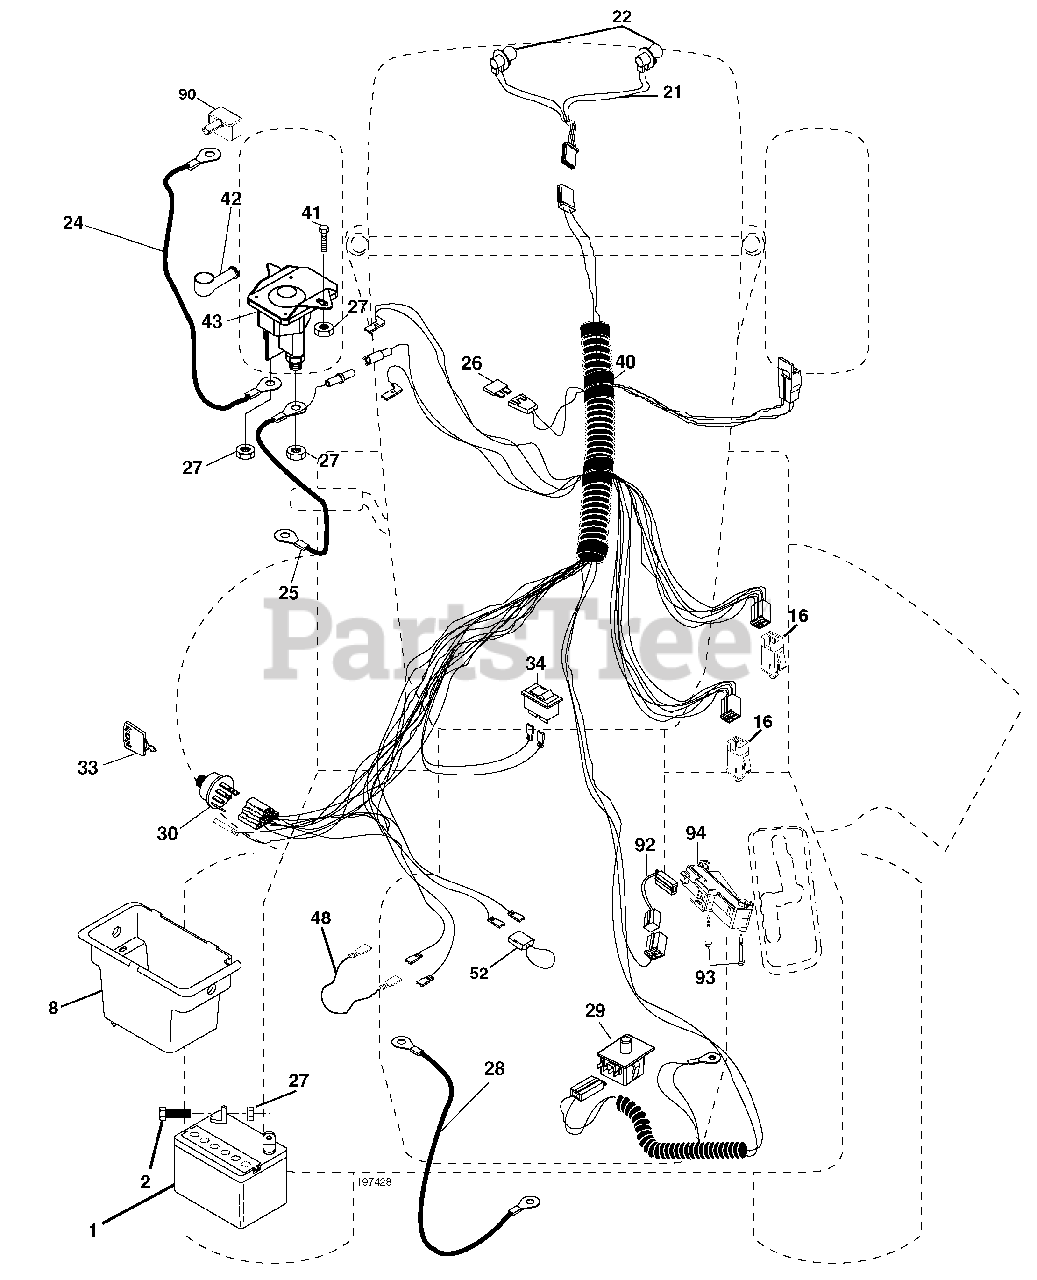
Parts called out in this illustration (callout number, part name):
1	Battery
2	Bolt Hex Hd 1/4-20 unc x 3/4
8	Box Battery
16	Switch Interlock
21	Harness Asm
22	Bulb Light #1156
24	Cable Battery 6 Ga. 11"red
25	Cable Battery
26	Fuse 20 AMP
27	Nut Keps Hex 1/4-20 unc
28	Cable Ground 6 Ga. 12"black
29	Switch
30	Switch Ign
33	Key Ign
34	Switch Light/Reset
40	Harness Ign
41	Bolt Blk Fin Hex 1/4-20
42	Cover Terminal Red
43	Solenoid
48	Adapter Ammeter
52	Protection Wire Loop
90	Cover Terminal Battery
92	Harness Pigtail
93	Screw Plastite 10-14 x 2.0
94	Module Reverse
